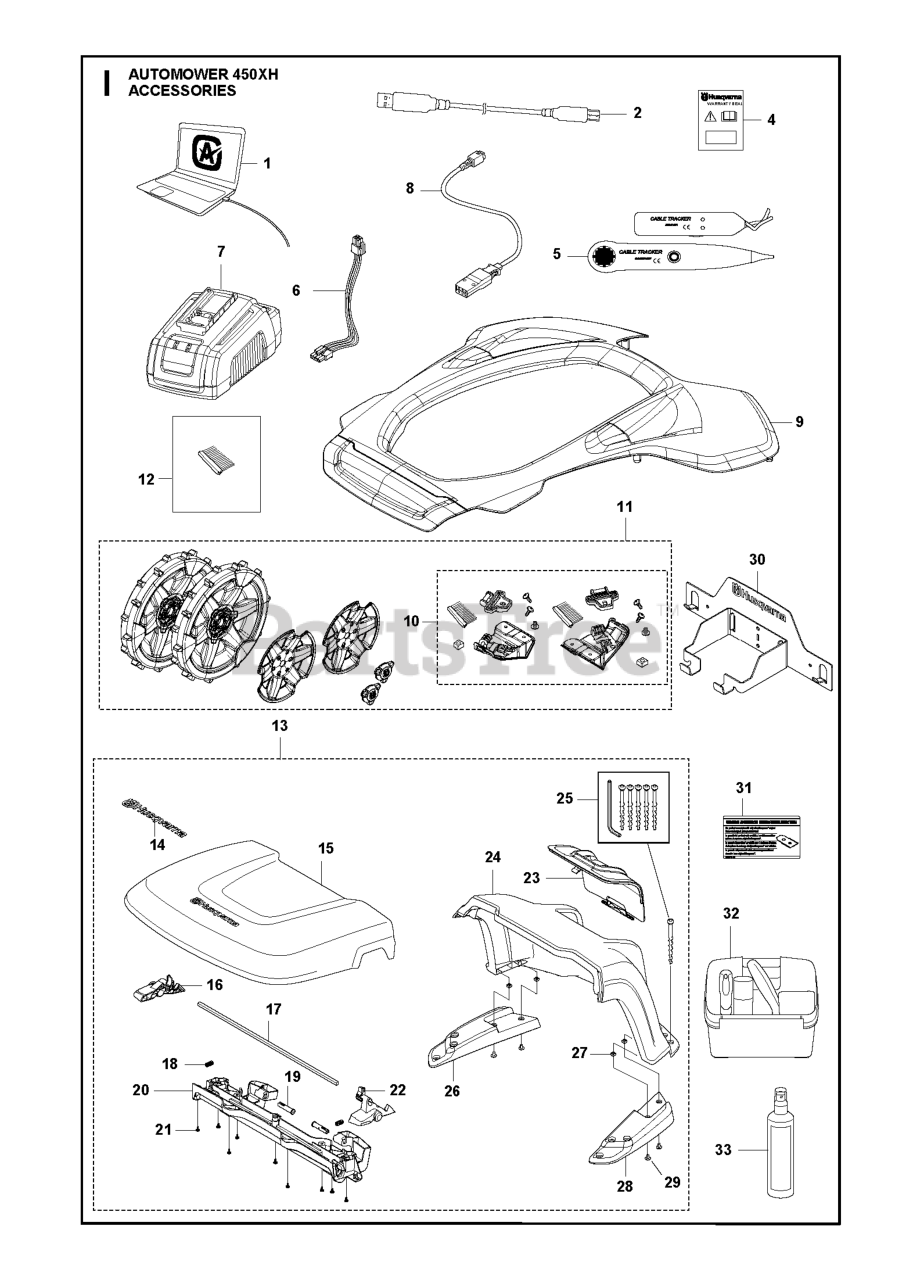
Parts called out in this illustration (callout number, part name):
2	CABLE WHITE ALT GREY
4	LABEL WARRANTY SEAL DEALER
5	TEST EQUIPMENT
6	WIRING ASSY BATTERY CABLE
7	CHARGER BATTERY TEST
8	CABLE ASSY QUICK CHARGER
9	BODY KIT
9	TOP COVER WHITE/ 450
9	TOP COVER ORANGE/ 450
10	BRUSH KIT 430/450
11	REAR WHEEL KIT W/ BRUSHES
12	WHEEL BRUSH REFILL KIT
14	DECAL
16	HANDLE RELEASE LEFT
17	ROD
18	SPRING SPRING CAP
19	HINGE PIN
20	BEAM
21	SCREW 14MM
22	HANDLE RELEASE RIGHT
23	HATCH
26	SUPPORT BASE LEFT
27	NUT
28	SUPPORT BASE RIGHT
29	SCREW IHPANM M6X25 4.6 ZP-BC
31	DECAL WARNING ORIGINAL BLADE E
32	CLEANING AND MAITENANCE KIT AM
